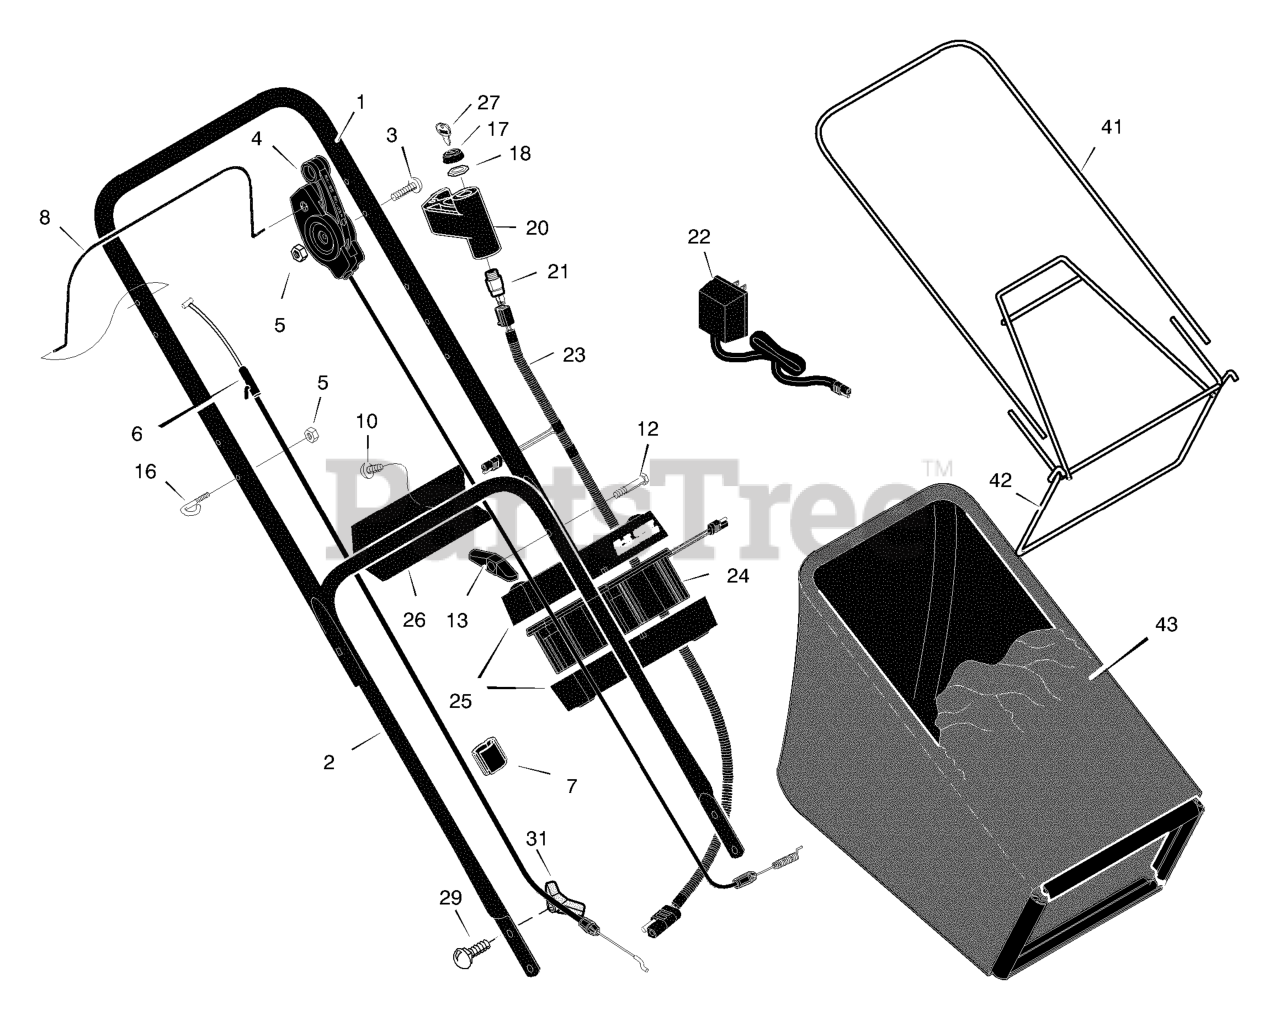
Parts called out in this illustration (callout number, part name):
1	Handle, Upper
2	Handle, Lower
4	Control, Drive
5	Locknut
6	Cable, Stop
7	Fastener, Cable
8	Lever, Stop
13	Knob
16	Guide, Rope
17	Cap
18	Nut
20	Case, Ignition
21	Switch Ignition & Key
22	Charger, Battery
23	Harness, Wiring
24	Battery
25	Case, Battery
26	Bracket, Battery
27	Key, Ignition
29	Bolt, Carriage
31	Knob, Plastic
41	Frame, Top
42	Frame Assembly
43	Bag, Cloth
